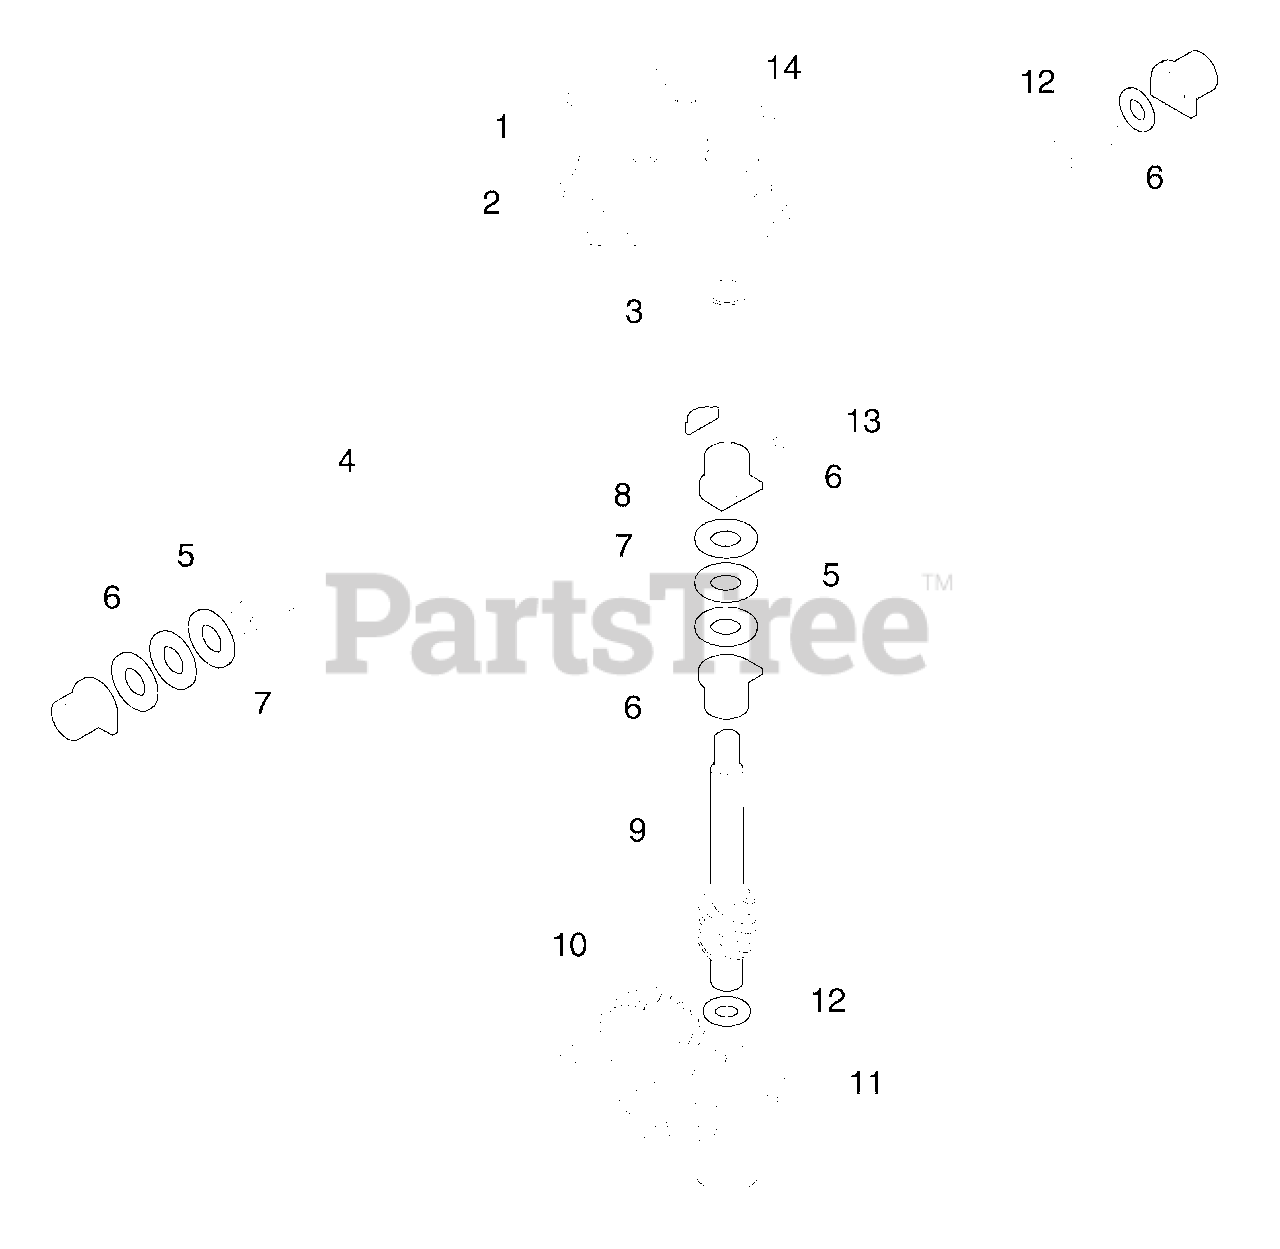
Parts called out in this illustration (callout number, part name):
1	Screw, Tapping #10-24 x .668
2	Gear Case, Upper
5	Bearing, Needle, Thrust
7	Washer, Thrust
10	Gear, Helical
11	Gear Case, Lower
12	Washer, Hardened
